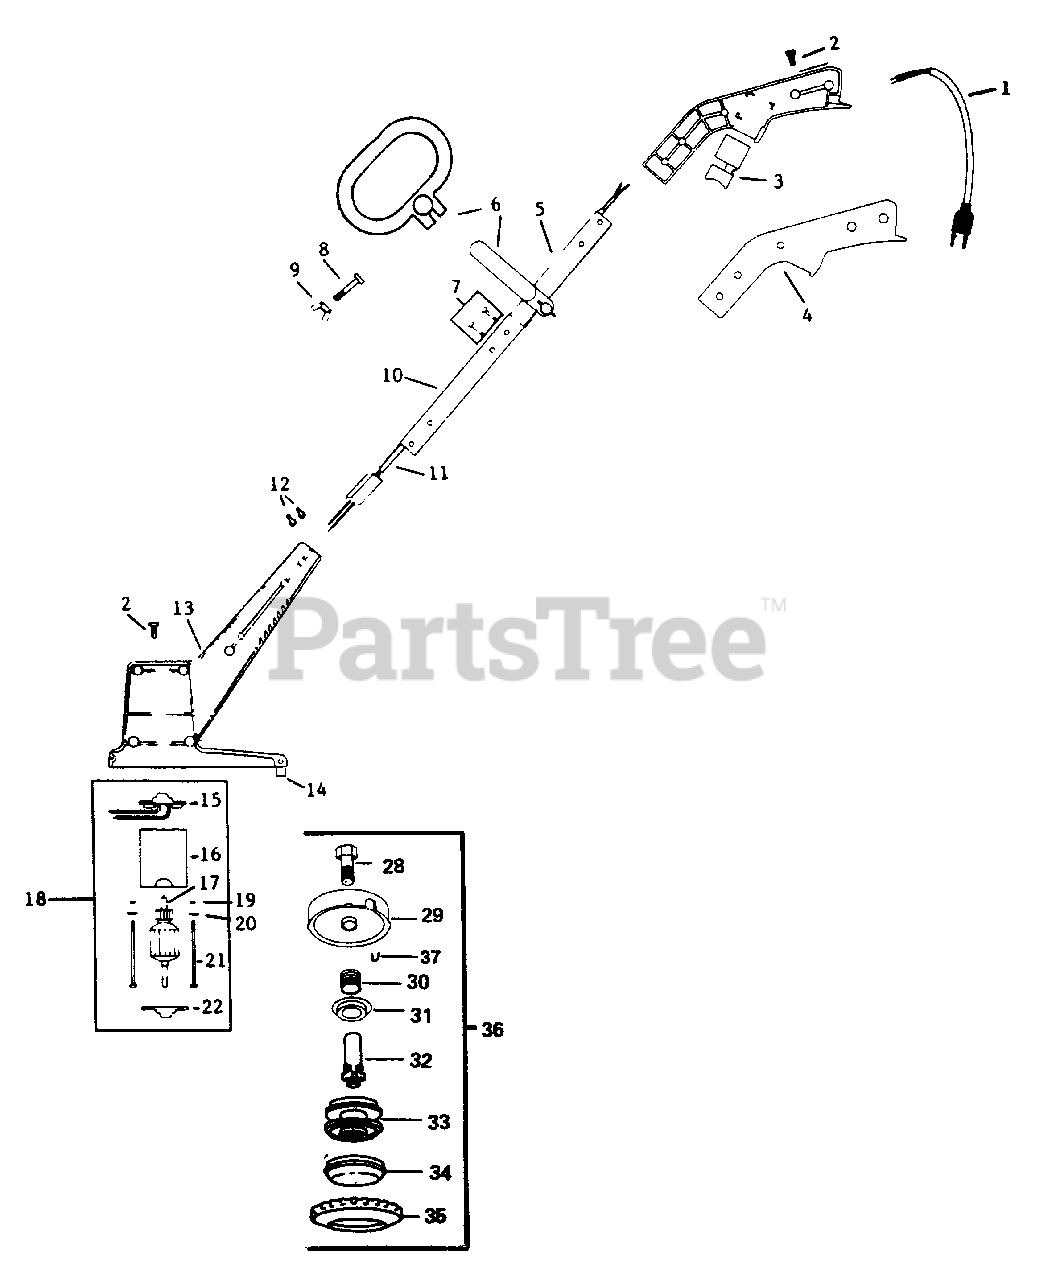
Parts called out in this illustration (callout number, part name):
1	POWER CORD PIGTAIL
4	TRIGGER HANDLE (SET ONLY)
5	UPPER HANDLE TUBE
6	ASSIST HANDLE
9	WING NUT
10	LOWER HANDLE TUBE
12	CONNECTOR
13	MOTOR HOUSING (SET ONLY)
14	TAIL INTERFERENCE BLADE
15	END BELL w/BRUSHES AND SPRINGS
16	FIELD ASSEMBLY
17	ARMATURE
18	MOTOR (COMPLETE)
20	LOCK WASHER
22	ENDBELL, OUTPUT
28	DRIVE ADAPTOR
29	HUB w/LINE SAVER
30	COIL SPRING
31	COIL SPRING ADAPTOR
32	DRIVE GEAR
33	SPOOL, W/LINE
34	RELEASE BUTTON
36	TAP-N-GO HEAD ASSEMBLY
37	LINE SAVER
